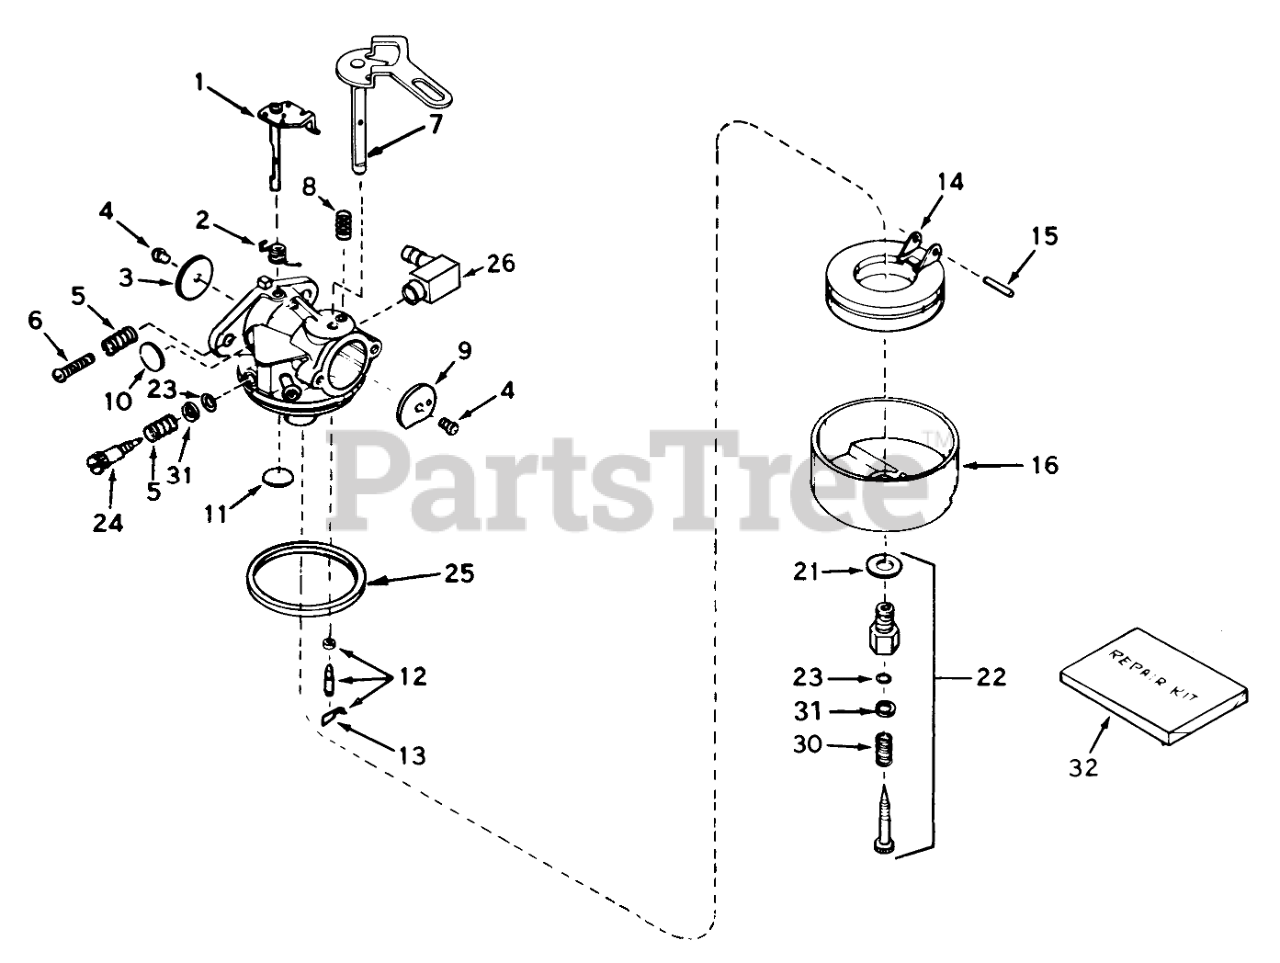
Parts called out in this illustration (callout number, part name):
1	Throttle Shaft and Lever ASM
2	Spring, Return
3	Shutter-Throttle
4	Screw-Shutter
5	Spring-Tension
6	Screw-Throttle Crack Screw / Idle Speed
7	Choke Shaft and Lever Asm
8	Spring-Positioning, Choke
9	Shutter-choke
10	Plug-Welch, Idle Mixture Well
11	Plug-Welch, Atmospheric Vent
12	Inlet Needle, Seat & Clip Assy. (Incl. Ref. #13)
13	Clip-Spring
14	Float
15	Shaft-Float
16	Bowl-Float (no drain)
21	Washer-Bowl Nut
22	Adjustment Screw Assy., Main (Incl. Ref. #21, 23, 30 &31)
23	"O"Ring
24	Screw, Idle Adj.
25	O Ring-Bowl, Float
26	Fitting-Fuel
32	Kit-Repair
